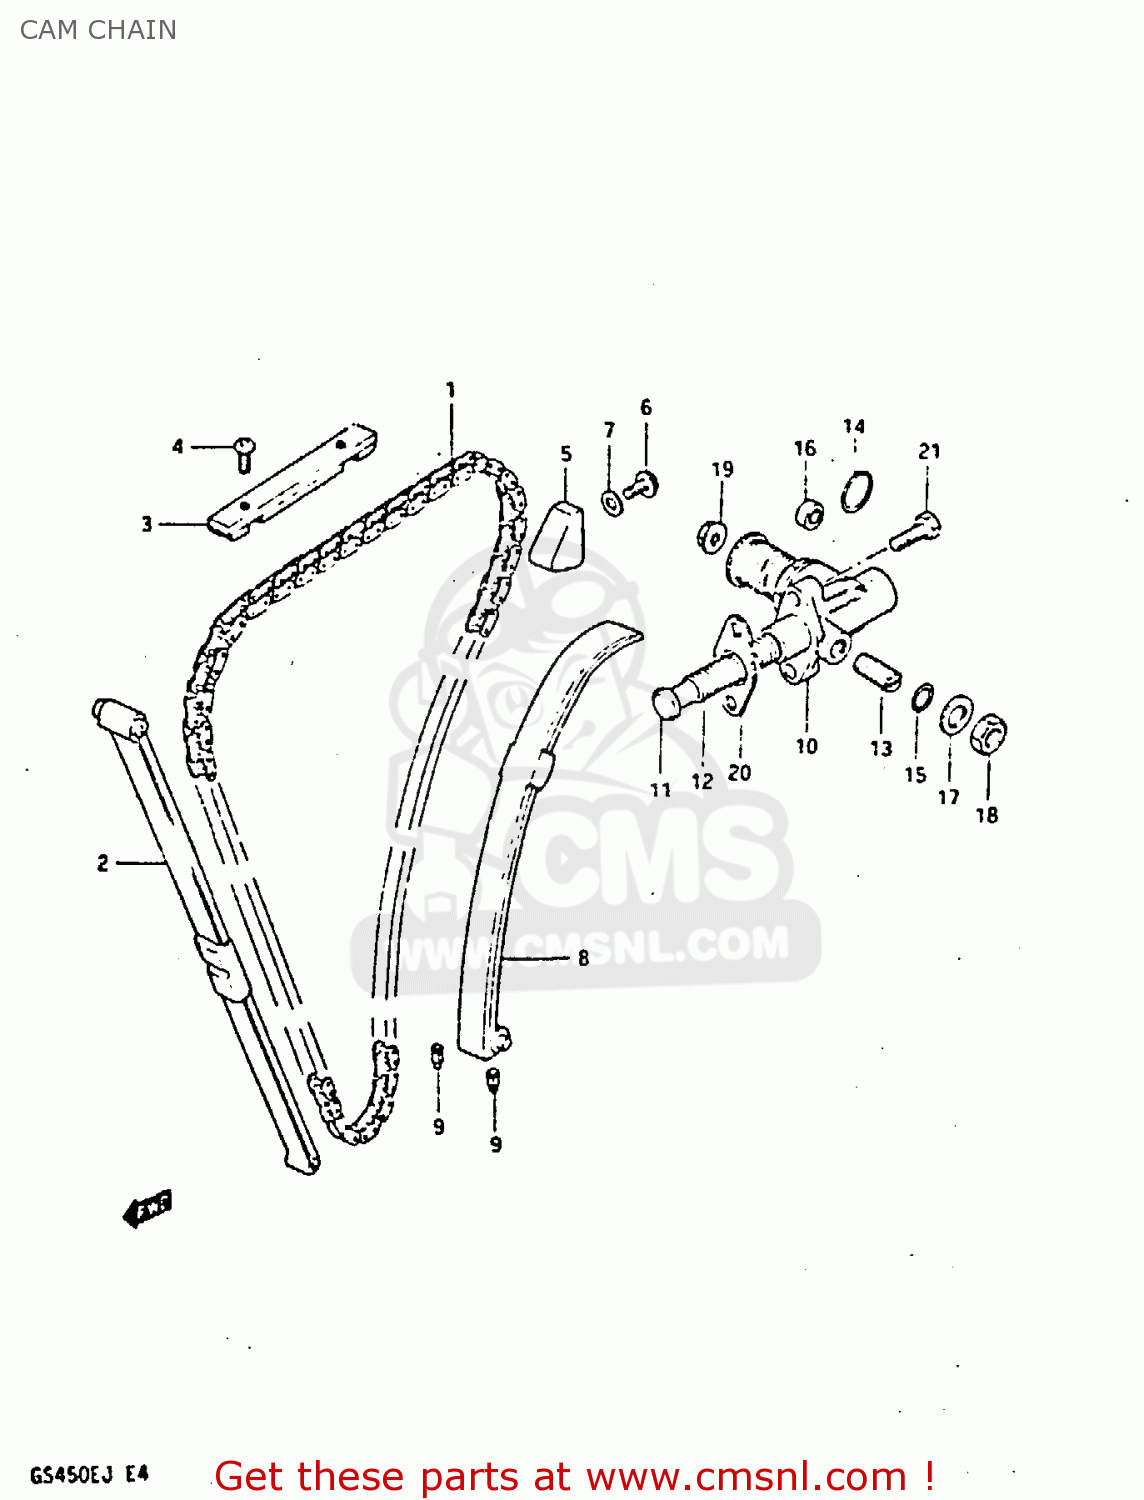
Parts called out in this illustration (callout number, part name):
1	CHAIN,CAMSHAFT DRIVE(120L)
2	GUIDE,CAM CHAIN NO.1
3	GUIDE,CAM CHAIN NO.3
4	SCREW
5	GUIDE,CAM CHAIN
6	BOLT 6X12
7	GASKET(5.8X13X1.2) (NAS)
8	TENSIONER,CAM CHAIN
9	CUSHION,CAM CHAIN TENSIONER
10	ADJUSTER ASSEMBLY,TENSIONER
11	ROD,PUSH
12	SPRING
13	SCREW,TENSIONER ADJUST
14	O RING(D:2.4,ID:20.8)
15	O RING(D:1.9,ID:5.7)
16	SEAL,OIL(10X16X4)
17	WASHER
18	NUT
19	NUT 6MM
20	GASKET,TENSIONER ADJUSTER (MCA)
21	SCREW
